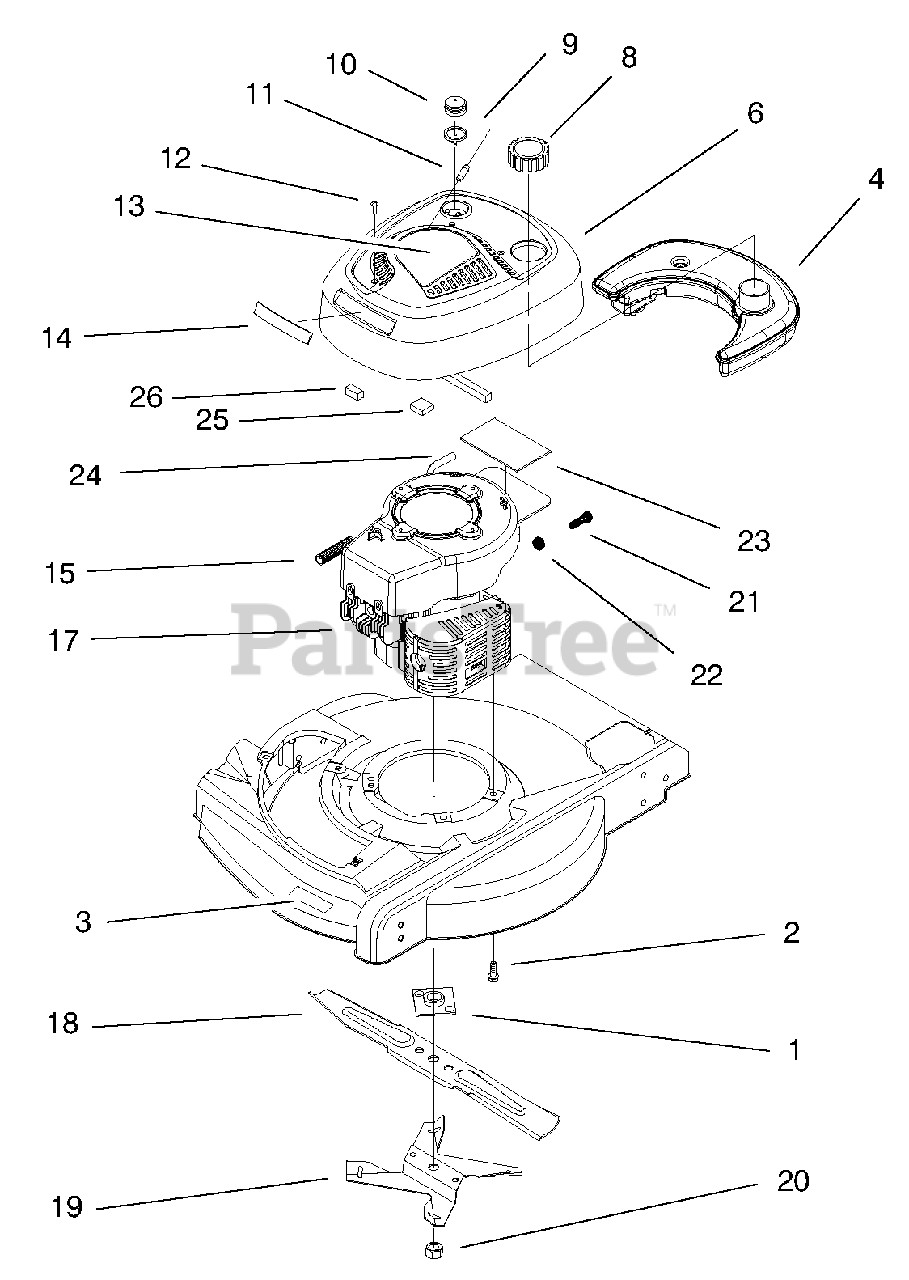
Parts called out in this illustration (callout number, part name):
1	Plate & Collar ASM
2	Screw-HH
6	ASM-Shroud/Recoil Cover
8	Assembly-Cap, Fuel/Oil
9	Body-Primer
10	Bulb-Primer
11	Rope-Stop
12	Screw-Pan Sems
13	Decal-Recoil
14	Applique-Shroud
15	Spring-Compression
17	Engine Ay HP E Silver
18	Blade-21" Whirl
19	Fan-Mulching
20	Nut-Blade
21	Screw-Sems
22	Nut-Hex
23	Pad-Foam
24	Line-Gas
25	Strip-Foam
26	Strip-Foam
